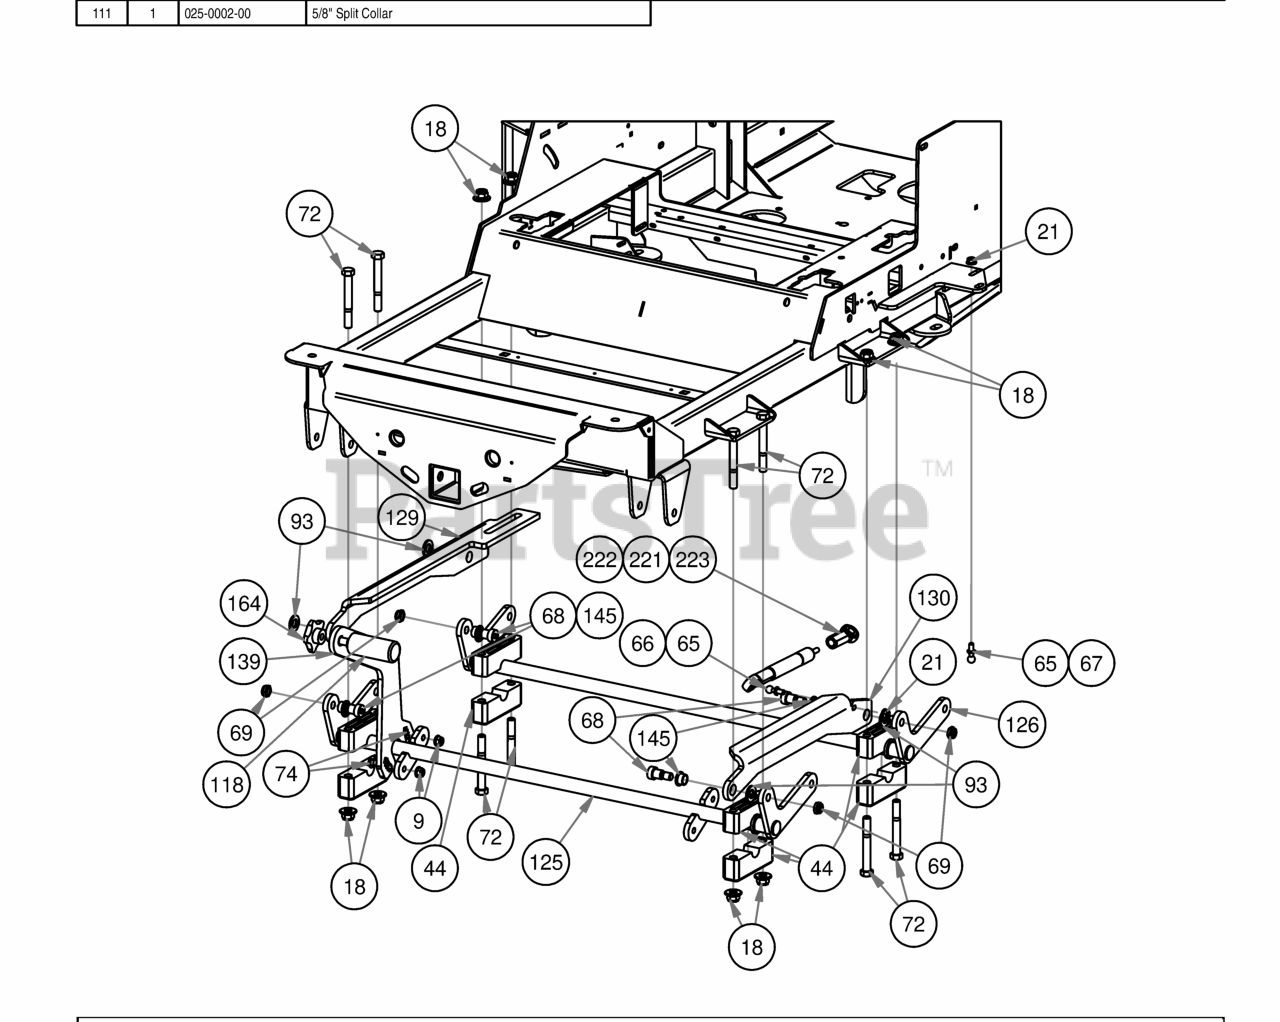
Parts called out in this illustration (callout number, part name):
9	3/8" Nylock Flange Nut
18	1/2-13 Nylon Flange Nut
21	5/16" Flange Nut
44	Pillow Block Assembly
65	13mm Damper Ball Stud-Steering
66	10mm Damper Ball Stud-Steering
67	10mm Damper Ball Stud-XP Linkage
68	5/8'' x 5/8'' Shoulder Bolt
69	1/2" Nylcock Nut (1/2 Jam)
72	1/2" x 4" Bolt (Grade 8)
74	3/8" x 1 1/4" Carriage Bolt
93	.630 ID Plastic Washer
118	Knurled Pedal
125	2019 Outlaw Actuator - Front
126	2019 Outlaw Actuator - Rear
129	2019 Actuator Linkage - Right
130	2019 Actuator Linkage - Left
139	Foot Lift Upright Lever
145	Bronze Bushing - SF - 2024-8
164	Foot Pedal Knob 1/2-13
203	2019 Veritical Suspension Frame
221	200 lb Gas Spring- 54" Deck outlaw
222	250lb Gas Spring - 61" Deck
223	300lb Gas Spring - 72" Deck
